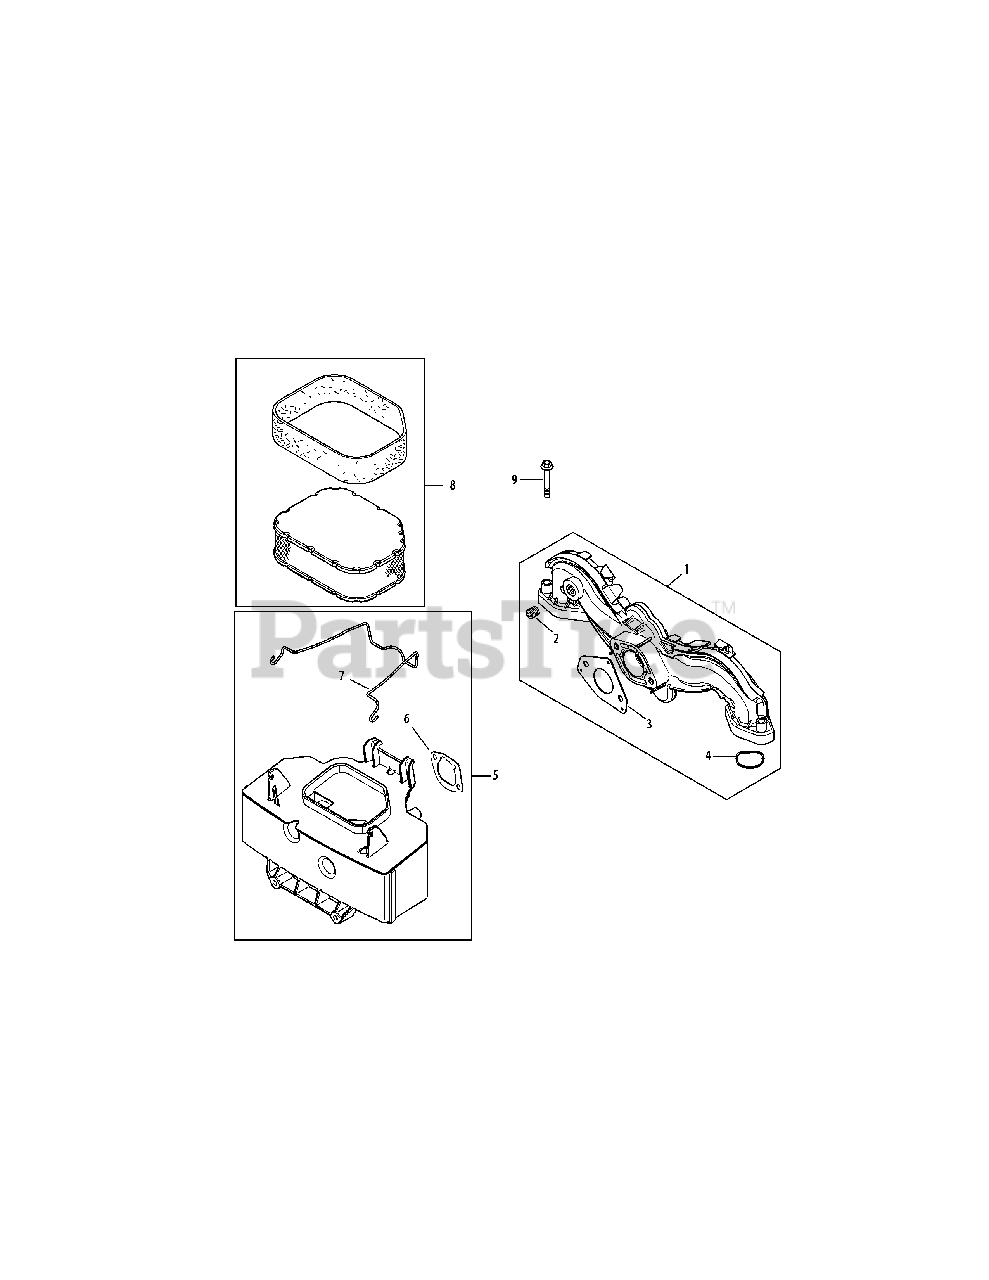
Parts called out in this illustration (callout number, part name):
1	Intake Manifold Kit (Inc. 2-4)
2	Carburetor Gasket
3	Intake Port O-Ring
4	Ctsk. Pipe Plug, 1/8
5	Air Cleaner Base Kit (Inc. 5 & 6)
6	Air Cleaner Base Gasket
7	Air Cleaner Element Latch
8	Air Filter Element / Pre-Cleaner
9	Flg. Screw, M6 X 1.0 X 40
